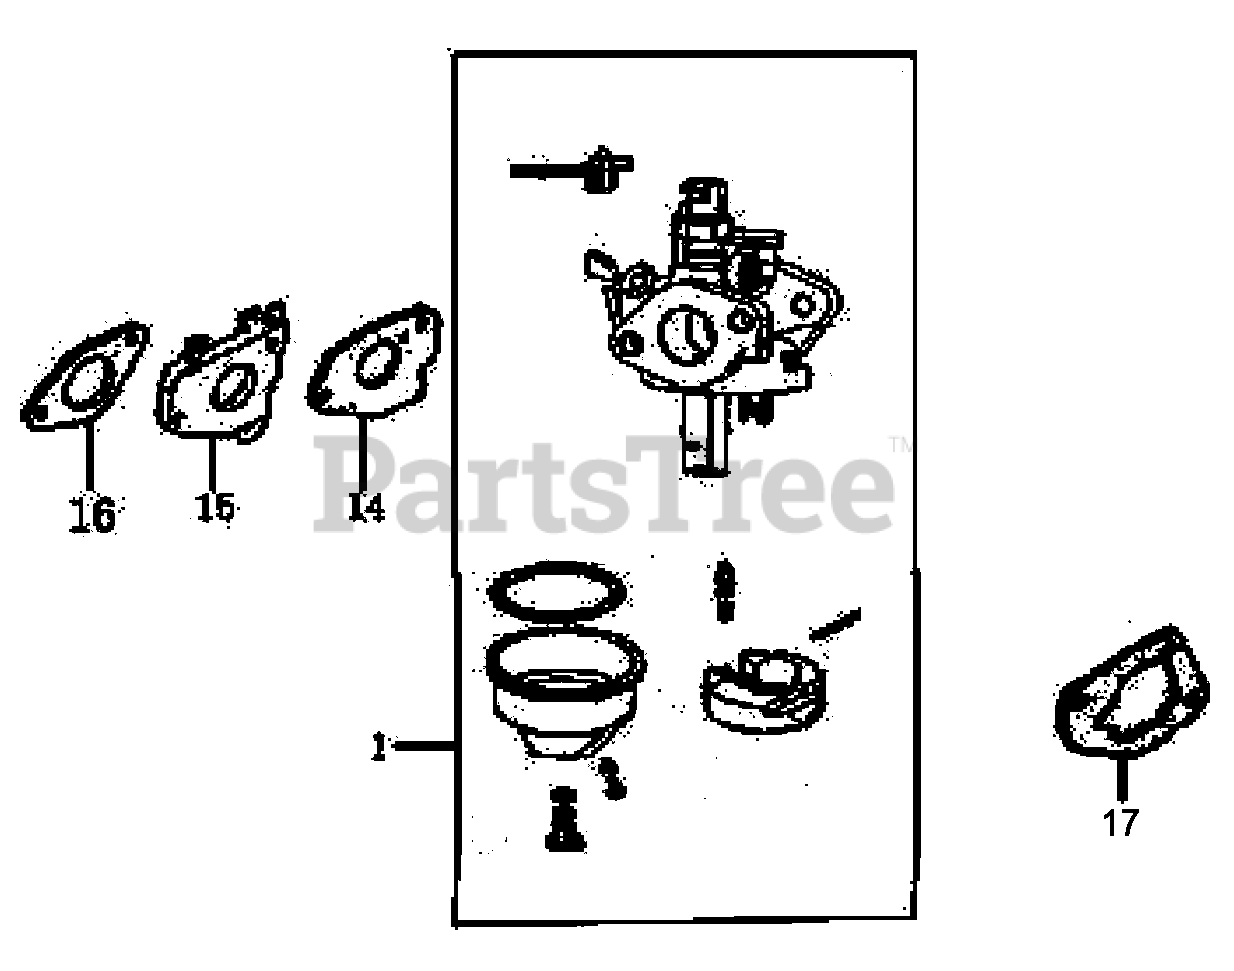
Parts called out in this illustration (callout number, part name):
1	CARBURETOR
14	GASKET, CARBURETOR
15	INSULATOR, CARBURETOR
16	GASKET, INSULATOR
17	GASKET, INSULATOR
